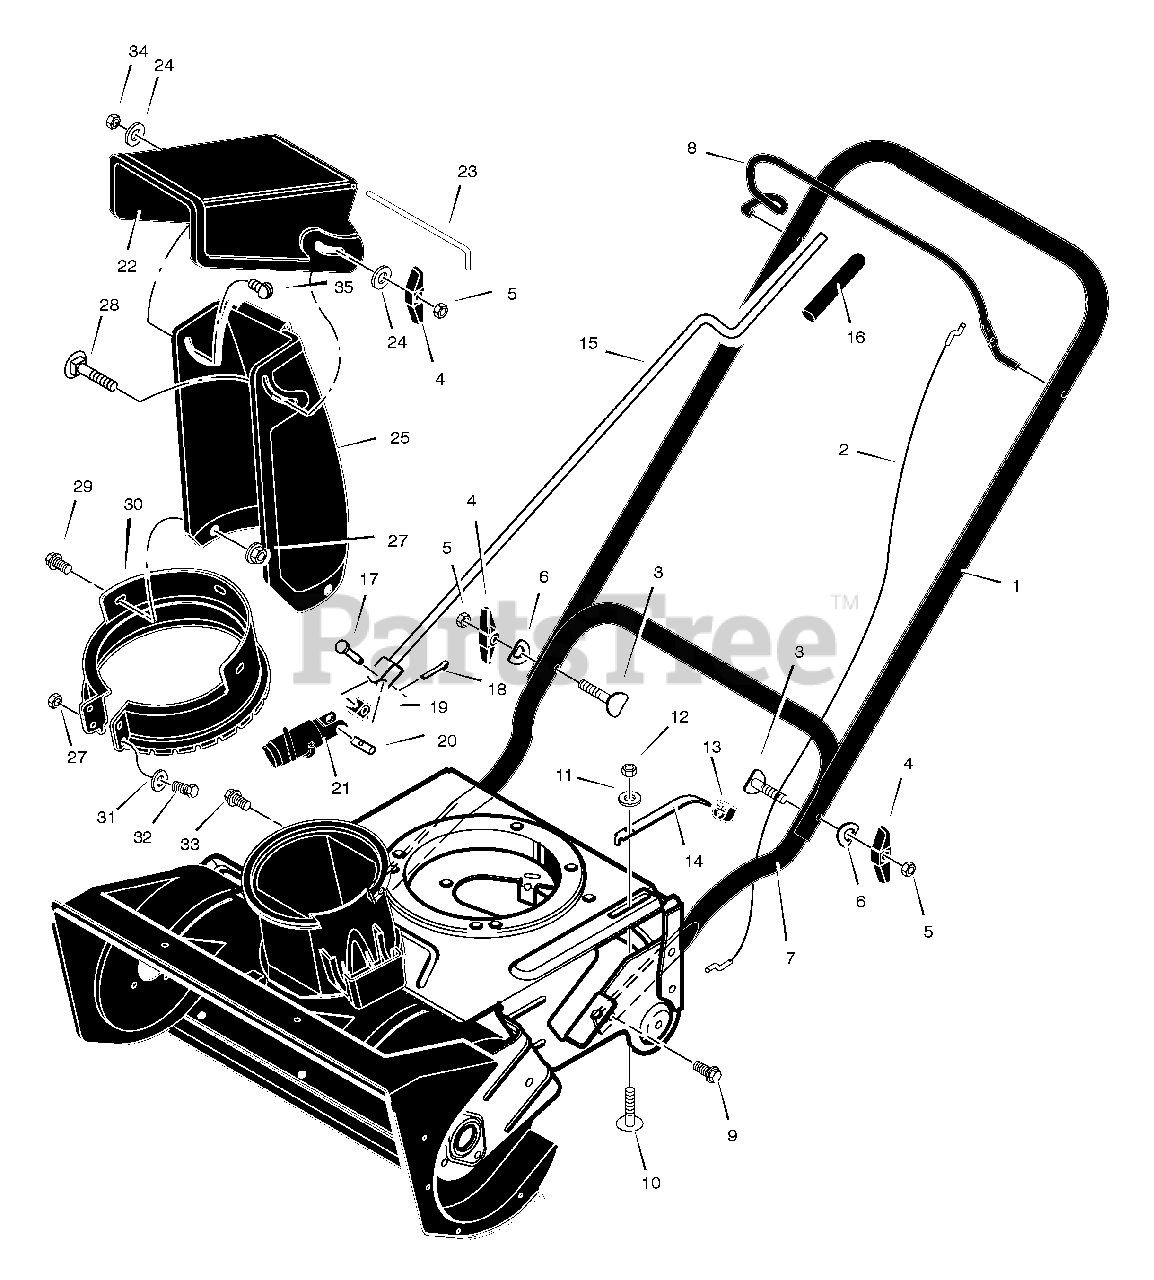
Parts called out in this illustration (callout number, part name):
1	Handle, Upper
2	Cable, Auger Drive
4	Knob
5	Nut
7	Handle, Lower
8	Lever, Auger Drive
9	Screw
10	Bolt
11	Washer
13	Bushing, Tensioner
14	Bracket, Cable Tensioner
15	Rod, Crank
16	Grip, Crank Rod
17	Pin, Clevis
18	Pin, Cotter
19	Block, Universal Pivot
21	Gear, Worm
22	Deflector
23	Pin, Pivot
24	Washer
25	Chute, Discharge
30	Ring, Chute
31	Washer
34	Locknut
